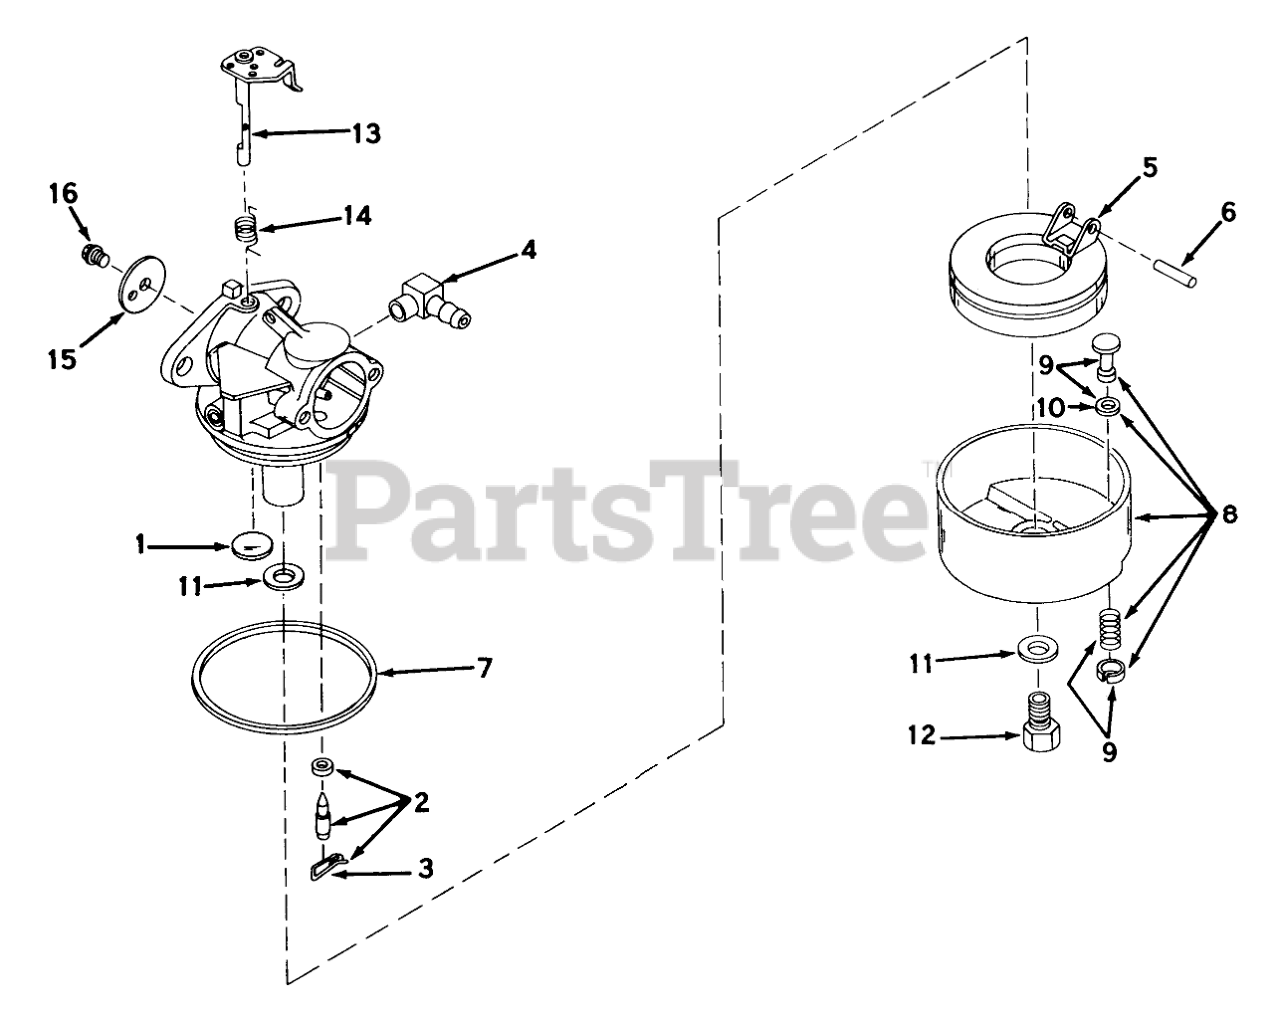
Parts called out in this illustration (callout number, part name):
1	Plug-Welch, Atmospheric Vent
2	Inlet Needle, Seat & Clip Assy. (Incl. No. 3)
3	Clip-Spring
4	Fitting Fuel Inlet
5	Float,Carburetor
6	Shaft-Float
7	O Ring-Bowl, Float
8	Bowl & Drain Assy., Float (Incl. No. 9)
9	Plunger Assy., Drain (Incl. No. 10)
10	Gasket-Plunger, Drain
11	Gasket-Bowl
12	Nut, Float Bowl
13	Throttle Shaft and Lever ASM
14	Spring, Return
15	Throttle-Shutter
16	Screw-Shutter
